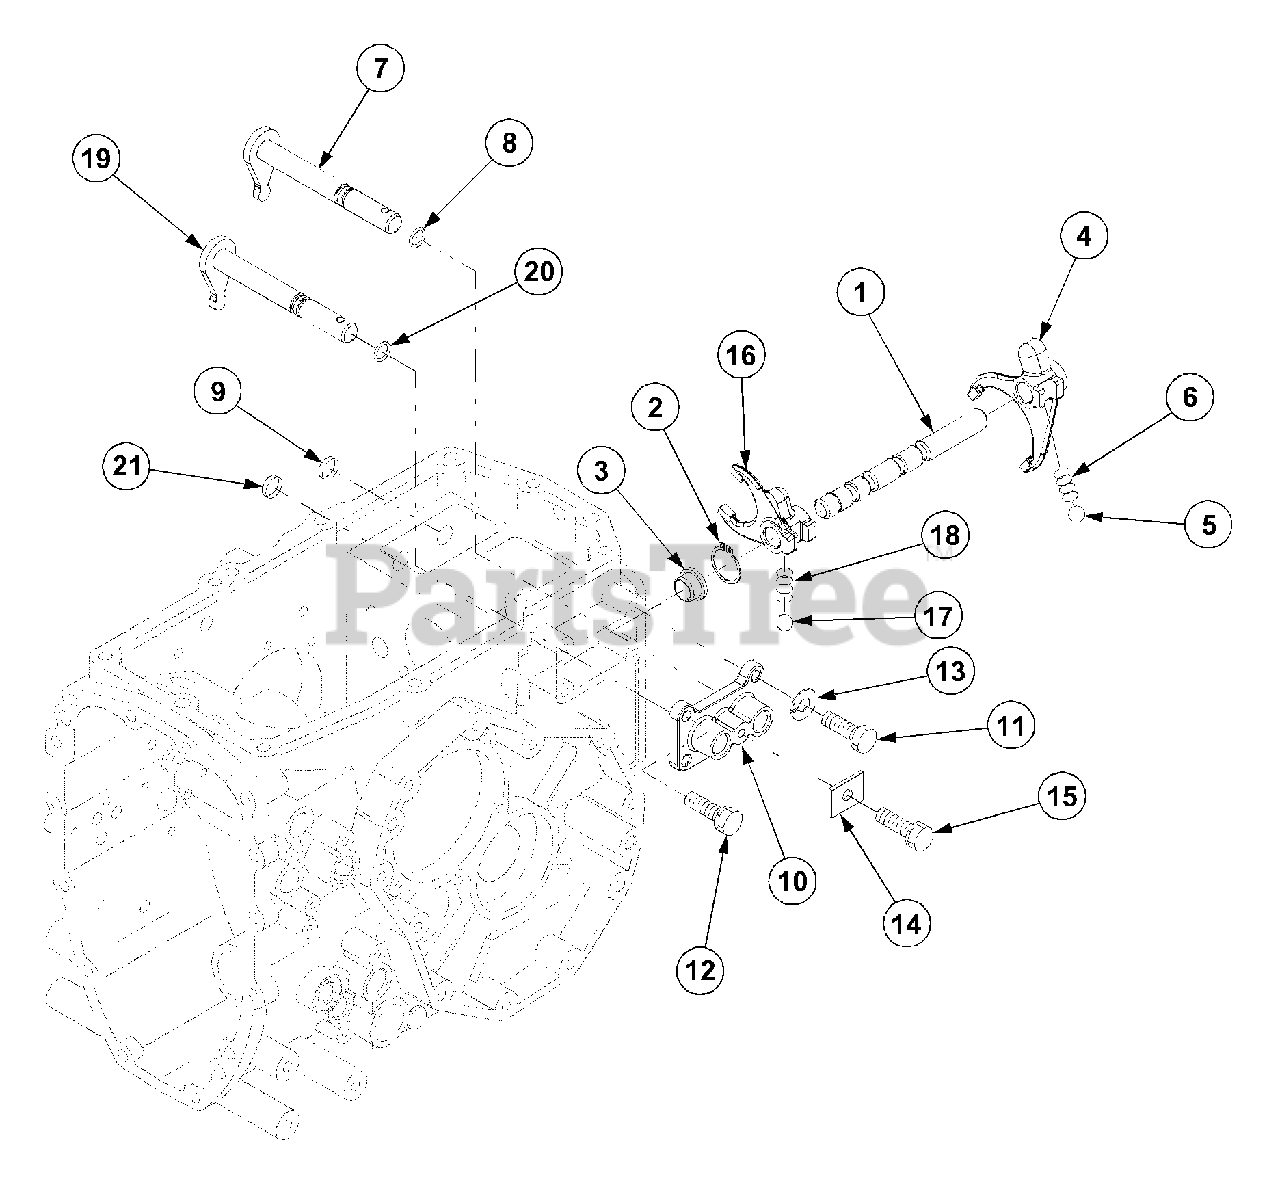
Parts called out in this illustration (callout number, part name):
2	C-ring
4	Fork,Rear PTO
8	O-Ring
12	Bolt,w/Washer
13	Washer,Spring
15	Bolt,w/Washer
20	O-Ring
